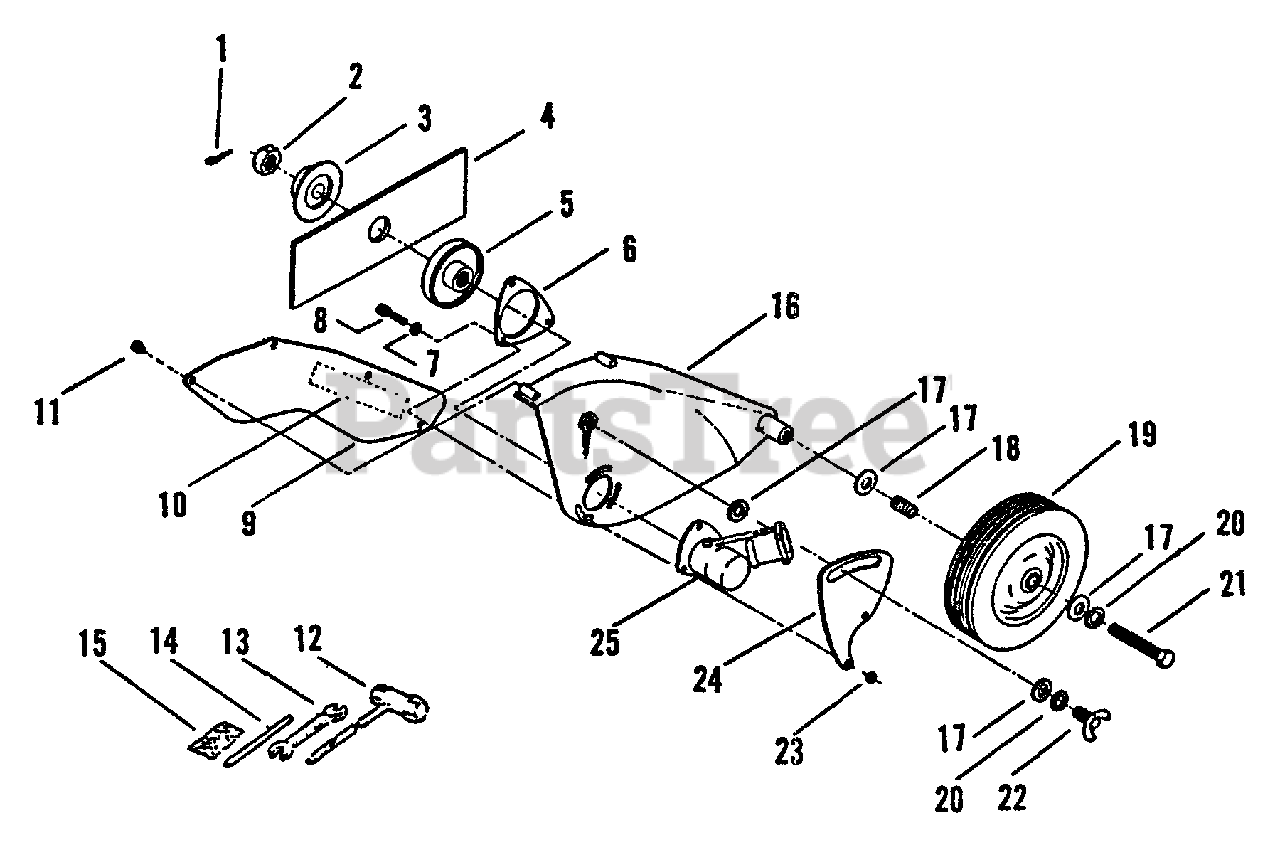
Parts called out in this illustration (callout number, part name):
1	PIN, SPLIT - 2X22
2	NUT - 10 -- LEFT HAND
3	ADAPTOR, BLADE - LOWER
4	BLADE, EDGER
5	ADAPTOR, BLADE - UPPER
6	PLATE, SHIELD
7	SCREW - 5X25
8	WASHER - CONICAL
9	COVER, SHIELD
10	LABEL - CAUTION
11	SCREW - 4X10
12	T-WRENCH - 17X19mm
13	SPANNER - 8X10mm
14	LOCKING TOOL
15	PIN, SPLIT - 2X22
16	SHIELD, DEBRIS
17	WASHER - 8
18	COLLAR - 12
19	WHEEL - 6X1.5
20	WASHER - 5
21	BOLT - 8X60
22	THUMBSCREW
24	BRACKET, SHIELD
25	GEAR CASE ASSY
